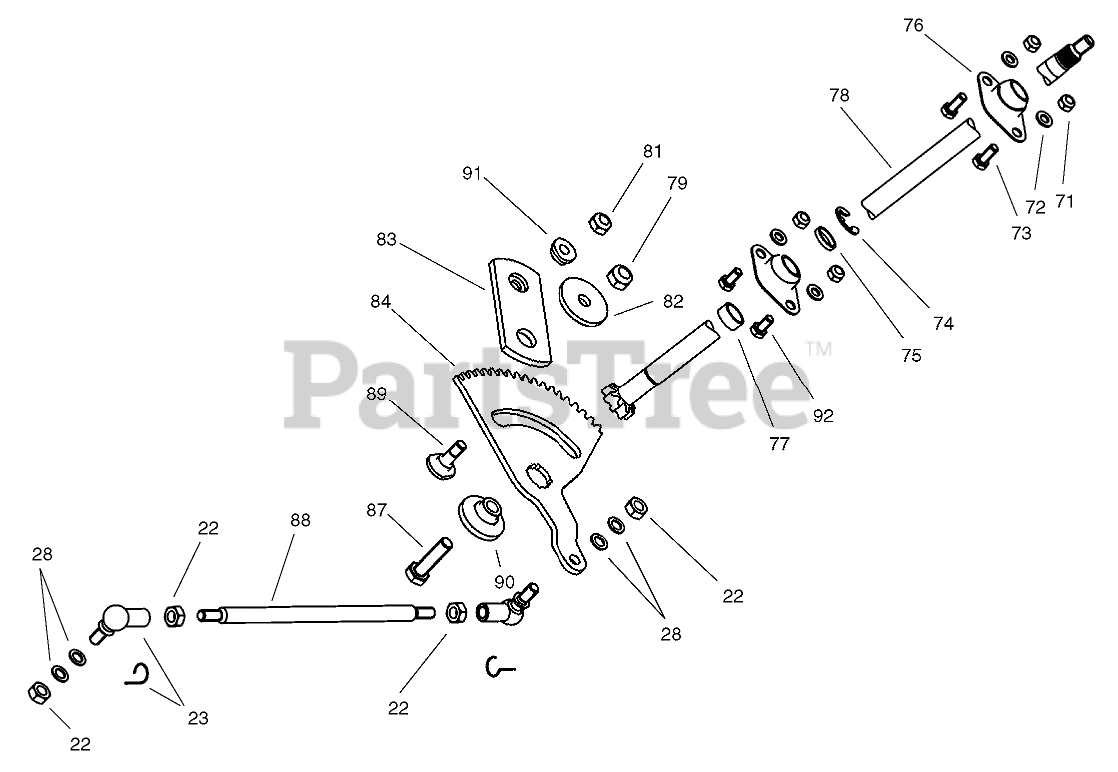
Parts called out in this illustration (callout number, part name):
22	NUT-HEX
23	Hsg-Ball Angle
28	Washer
71	NUT-LOCK, NI
72	WASHER-PLAIN
73	SCREW-HH
74	CLIP-SPRING
75	SPACER-UPPER
76	BEARING-SPHERICAL
77	SPACER-LOWER
78	Shaft-Steering
79	NUT-LOCK
81	NUT-LOCK, NI
82	WASHER-PLAIN
83	Plate-Steering
84	GEAR-SECTOR
87	SCREW-HH
88	LINK-DRAG
89	Bolt-Shoulder
90	Pivot-Steering
91	Bushing
92	SCREW-HH
